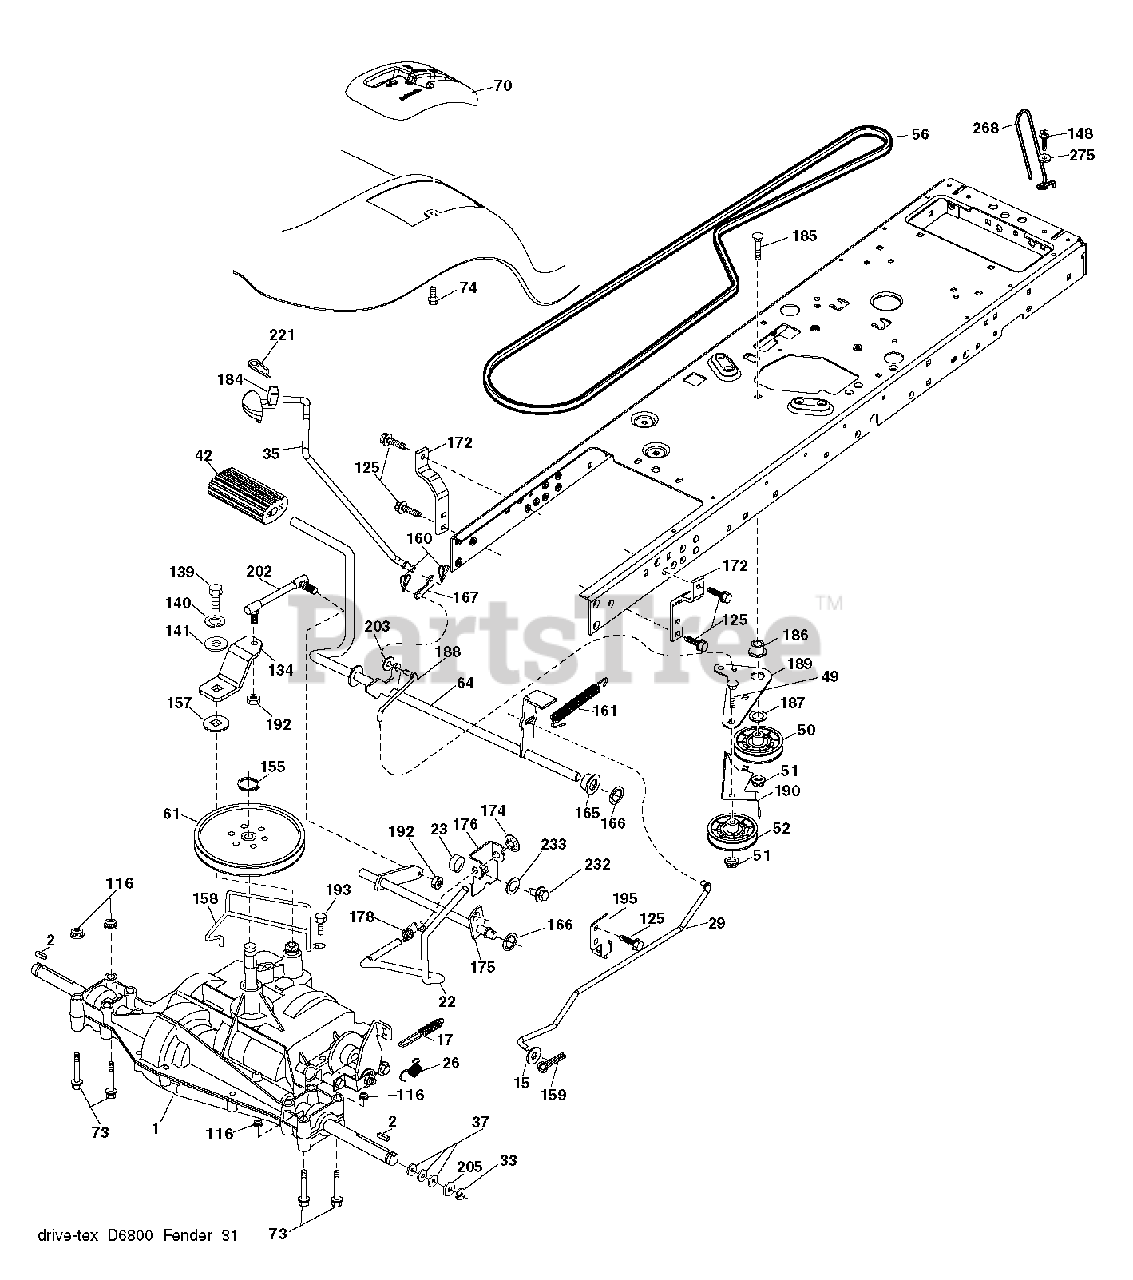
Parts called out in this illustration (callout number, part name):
2	SQUARE KEY
17	SPRING.BRAKE.PEERLESS.TEX
22	ROD.SHIFT.FENDER.TLT.2006
23	KNOB.DUCKHEAD.1/2
26	SPRING.BRAKE.RTN.GR.DR
29	ROD.BRAKE.PEERLESS
33	E-RING LT
35	ROD.BRAKE.PARKING.LT.T
42	PEDAL COVER T
49	BOLT
50	IDLER.FLAT.910.OFFSET
51	NUT LOCK FLG 3/8-16 UNC
52	IDLER.V-GROOVE.910.OFFSET
61	PULLEY TRANS
64	SHAFT.ASM.PEDAL.BRAKE.
70	CONSOLE.SHIFT.
73	BOLT HEX 5/16-18 GR 5
74	SCREW.HI-LO.CONSOLE
116	NUT LOCK HEX FLANGE 5/16-18
125	SCREW
134	ARM.SHIFT.
139	BOLT 1/4-28X3/4
140	LOCKWASHER
141	WASHER LT
148	SCREW, 3/8-16X3/4
155	RETAINING RING LT
157	WASH-SHFT PLT LT
158	KEEPER.PMS.18/20.D4365
159	COTTER PIN
160	RETAINER CLIP
161	SPRING.RETURN.CLUTCH.2006
165	BUSHING.SHAFT.BRAKE.HAND
166	NUT.PUSH.625.2006
167	LATCH.BRAKE.SPRING
172	STRAP.TRQ.LH.GEAR.DRIV
174	NUT.PUSH.500.2006
175	SHAFT.ASM.SHIFT.
176	ARM.CLEVIS.ROD.SHIFT
178	SPRING.SHIFT.GT2006
184	HANDLE.PAKRING.BRAKE.
186	SPACER.RETAINER
187	WASHER 12/32X2X10GA
188	LINK.CLUTCH.GROUND.DRIVE
189	BELLCRANK.GROUND.DRIVE.TEX.
190	KEEPER.BELLCRANK.DRIVE
192	NUT LOCK CENTER 1/4 -28 FNTHD
193	SCREW 5/16"
195	BRKT.ROD.BRAKE.PEERLES
202	LINK.TRANSAXLE.
203	WASHER
221	RETAINER.SPRING.CLIP.H
232	BOLT FIN HEX 7/16-14 X 1
233	WASHER SERRATED
275	WASHER
